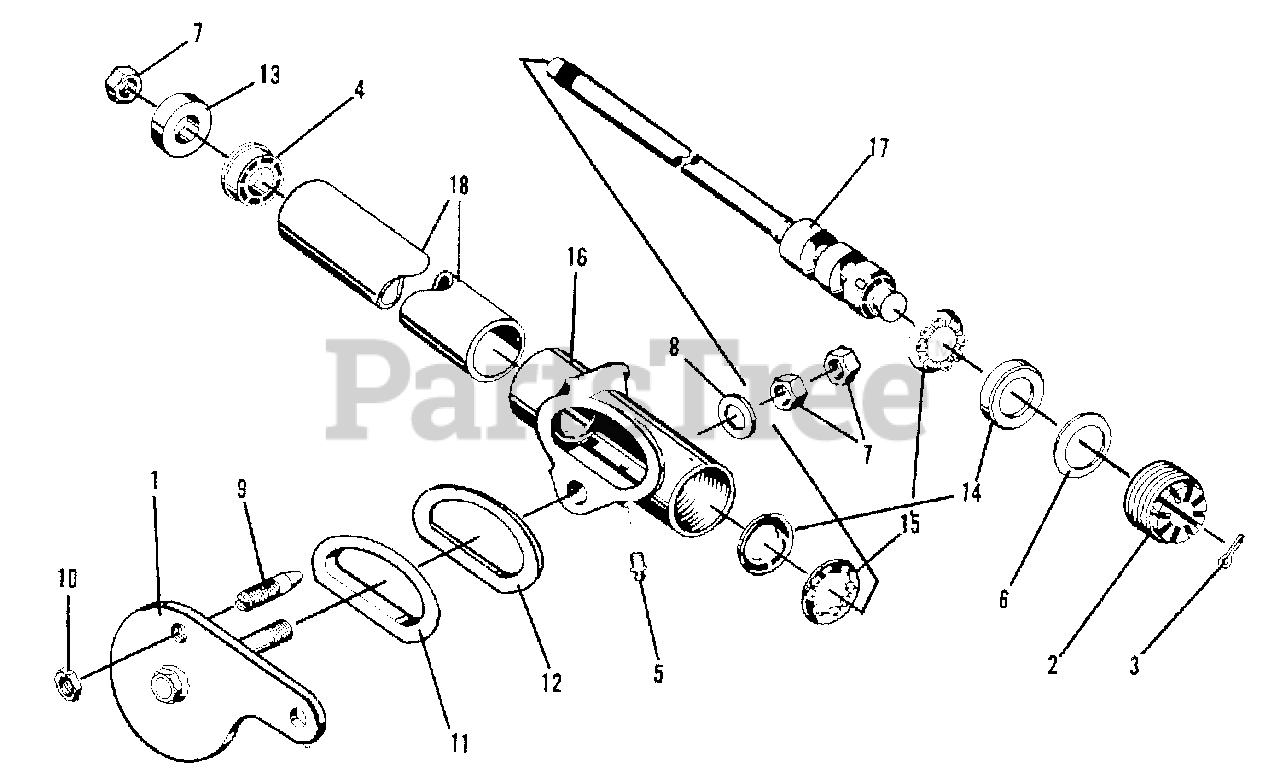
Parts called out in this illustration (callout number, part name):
1	LEVER & BOLT ASSEMBLY
2	PLUG, Adjustment
3	PIN, Cotter, 1/8 x 1/2, Platted
5	FITTING, Grease
6	WASHER, Bellville
7	NUT, Jam, 5/8-18, Hex.
10	NUT, Adjacent
11	RETAINER, Seal
13	SEAL, Dust
14	CUP, Ball (Includes Item 15)
15	BALL & RETAINER
16	HOUSING (Not Serviced)
17	CAM (Not Serviced)
18	TUBE, Jacket (Not Serviced)
